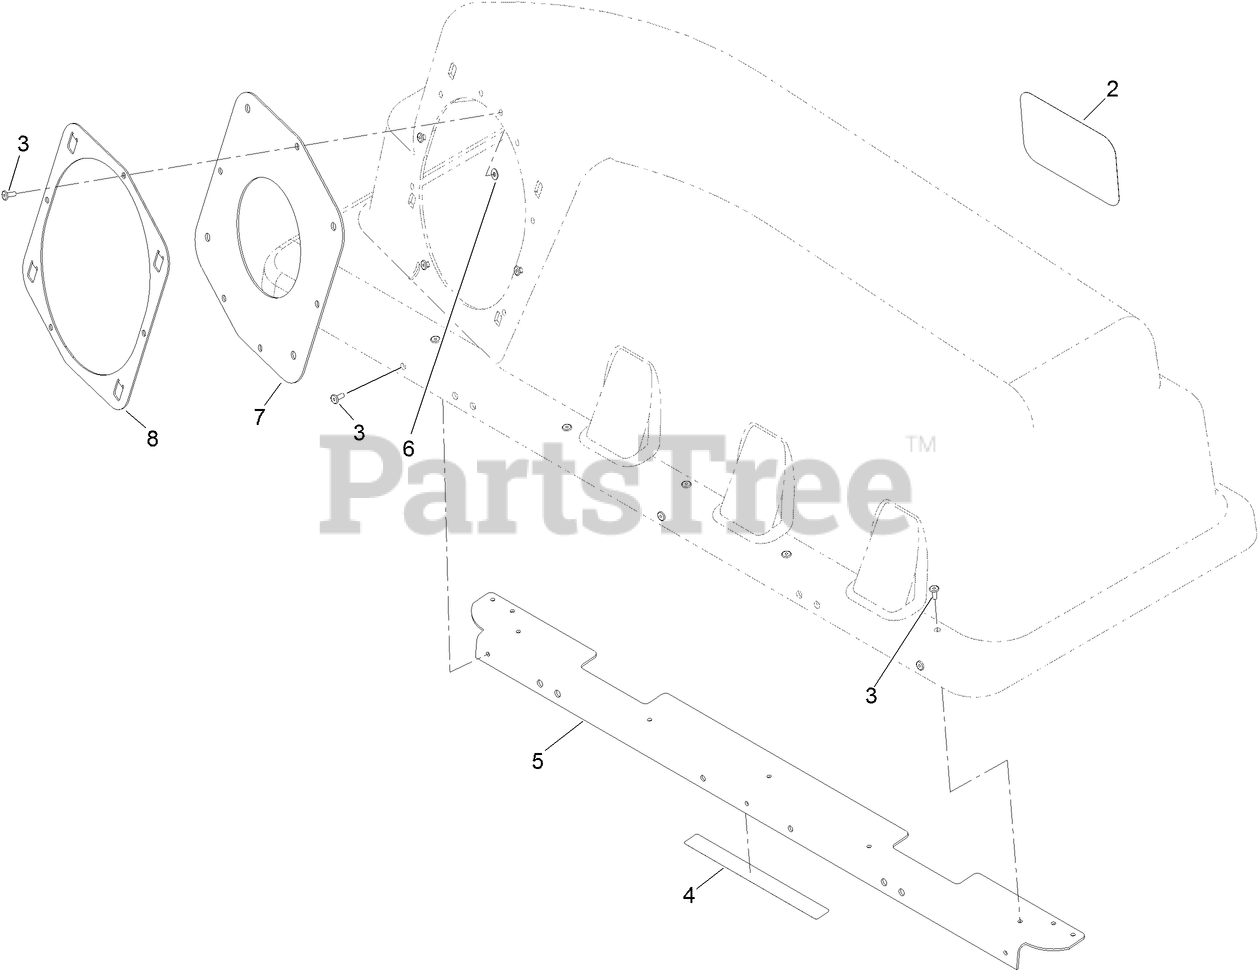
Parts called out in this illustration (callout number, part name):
2	DECAL
3	RIVET-BLIND
4	DECAL-CAUTION, BAGGER
5	STIFFENER-BAGGER, TOP
6	WASHER-FLAT
7	GASKET
8	RING-RETAINER
